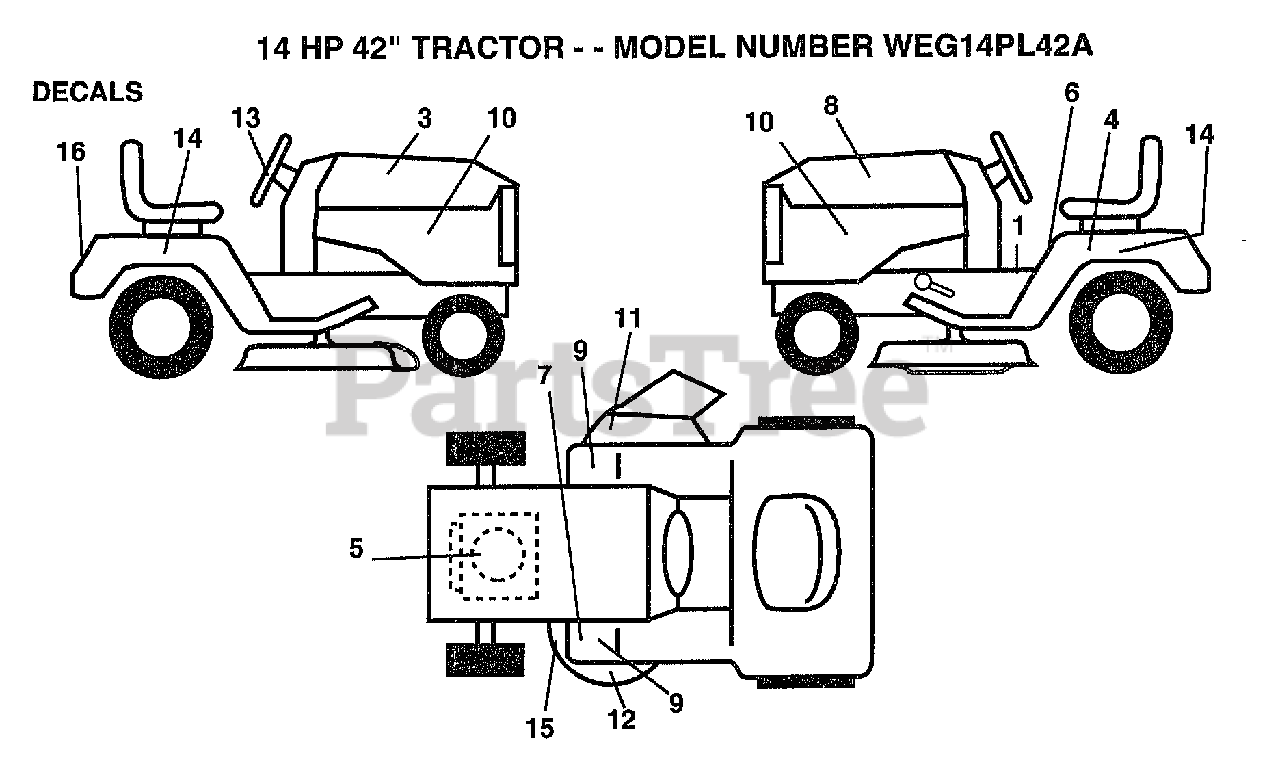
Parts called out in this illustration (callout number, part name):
1	DECAL DASH INS OP
3	DECAL.HD.RH.B&S
4	DECAL.FEND.QUICKS
5	DECAL ENGINE
6	DECAL CAUTION
7	DECAL T
8	DECAL.HD.LH.B&S
9	"PAD,FOOTREST"
10	DECAL.PANEL.SIDE
11	"DECAL, WARNING"
12	DECAL.MOWER
13	DECAL.WHL.STRG.
14	DECAL
15	DECAL.V.BELT
16	DECAL.FENDER
